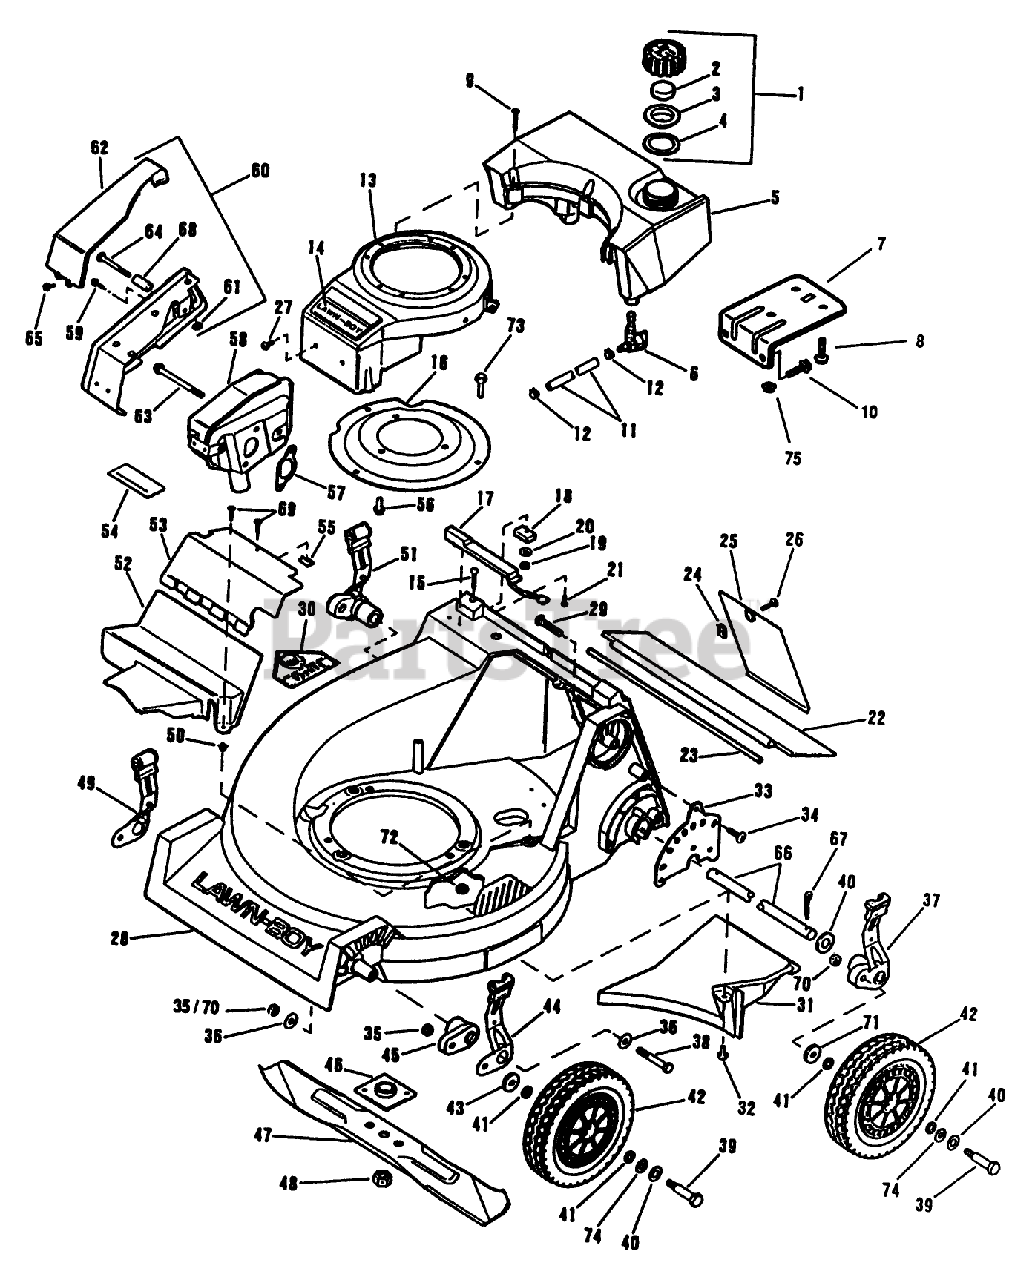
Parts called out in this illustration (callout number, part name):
1	CAP AY - F/OIL SM
2	BAFFLE - FOAM SM
4	GASKET-FUELCAP SM
6	DISC/LB SER.BUL.#6
7	DISC. LB SER.BUL.#6
8	DISC/LB SER.BUL.#6
9	DISC.LB SER.BUL.#6
11	GAS LINE SM
12	HOSE CLAMP SM
14	APPLIQUE SM
17	SWITCH AY DELTA
24	SPEED NUT LARSON
25	DOOR-ACCESS ELECT.
26	SCREW-CROSS RECESS
31	CHUTE BAFFLE NYL
33	PLATE HGT CMS
34	SCREW-BHTF
35	NUT-JAM, LOCKING
36	WASHER-PLAIN
37	HT. ADJ. ARM AY-L
39	BOLT WHEEL QUAL
40	SPACER
41	WASHER
42	WHEEL&TIRE 8" TRI
43	WASHER
44	KNOB & SPRING CMS
45	ARM HGT ADJ *BLACK
46	PLATE AND COLLAR ASM
48	NUT-BLADE
49	KNOB & SPRING CMS
50	NUT-CLIP
51	HT. ADJ. ARM AY-R
55	NUT-SPEED
57	GASKET - EXH SM
59	SCREW S
60	MUFFLER GUARD AY
61	NUT-PUSH
62	COVER MUFFLER CP
63	SCREW-SEMS
64	SCREW SM
65	SCREW SM
66	ROD HGT ADJ R GLM
68	SPACER S
69	SCREW S
70	LOCKNUT
71	WASHER WROUGHT
72	NUT-LOCK F
73	SCREW-HH
74	WASHER
